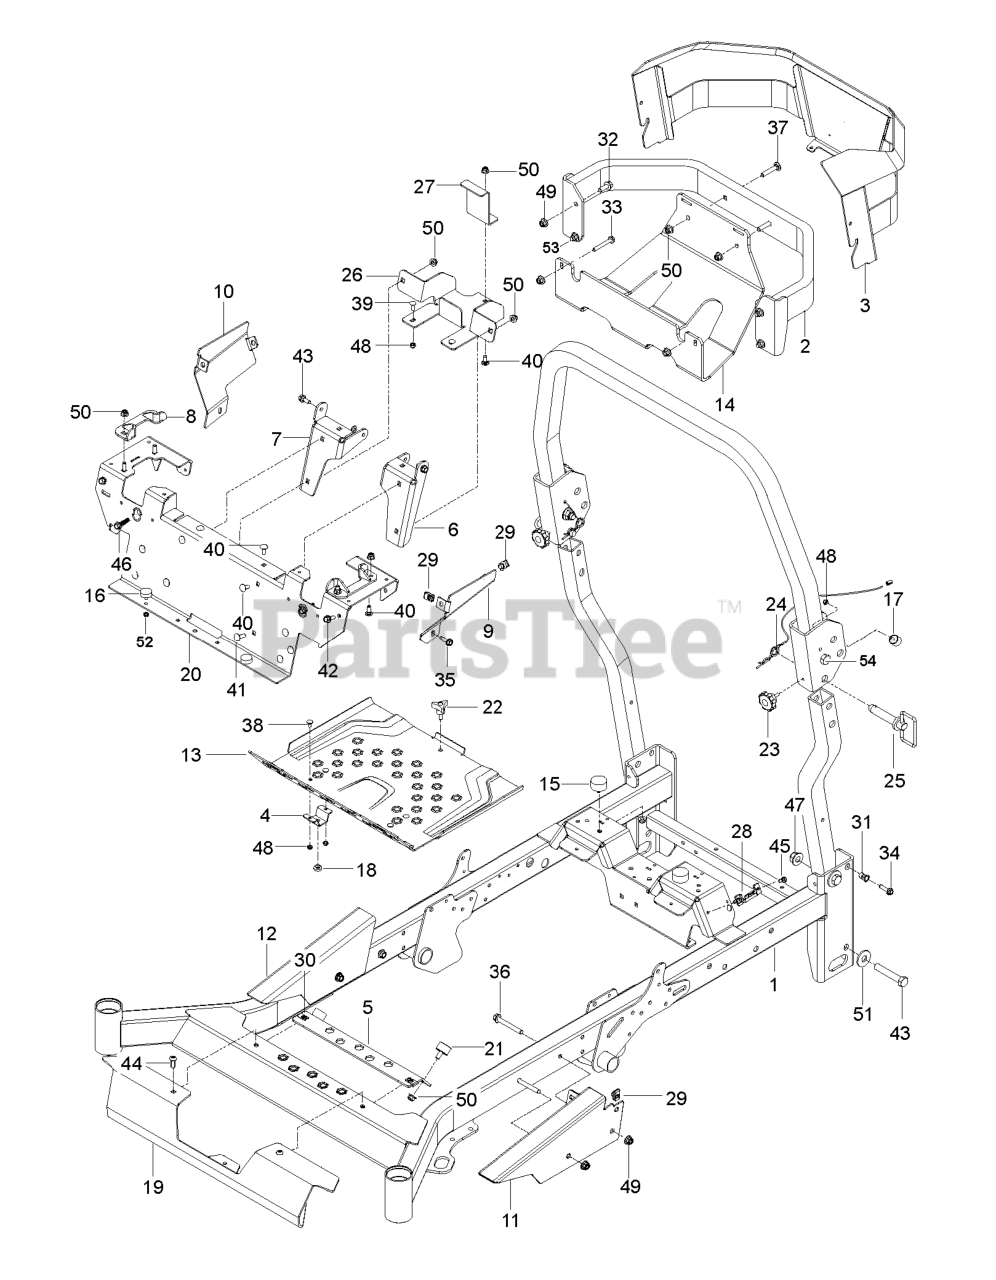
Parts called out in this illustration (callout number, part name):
1	FRAME.W/DECALS.48-60".ORG
2	BUMPER.REAR.ORANGE
3	GUARD.PNT.ENGINE.GREY
4	COVER.PNT.VALANCE.PZ.GREY
5	BRACKET.PNT.ISOLATOR.SUPPT.BLK
6	BRACKET.PNT.MTG.SEAT.LH.EDIP
7	BRACKET.PNT.MTG.SEAT.RH.EDIP
8	CABLE.YOKE.PARK.BRAKE
9	PANEL CLOSE OUT LH ORANGE MS-6
9	PANEL.PNT.CLOSE.OUT.LH.ORG
10	PANEL.PNT.CLOSE.OUT.RH.ORG
11	PANEL.PNT.WEDGE.LH.ORG
12	PANEL.PNT.WEDGE.RH.ORG
13	PLATE.PNT.FOOTREST.PZ.ORANGE
14	PLATE, SKID GRAY
14	PLATE SKID, Z500 LONG YAMAHA G
15	BUMPER 5/16-18
16	BUMPER, 1/4-20 STUD, 1/4
17	BUMPER, MALE STUD, 1/4-20
18	GROMMET, BUMPER
19	COVER.PNT.VALANCE.PZ.GREY
20	CROSS.MEMBER.PNT.SEAT.FRONT.OR
21	ISOLATOR.PZ.FOOTREST
22	KNOB W/STUD
23	KNOB.5/16-18X1"BLACK
24	PIN.HAIR.DOUBLE.LOOP.W/LANYARD
25	PIN.ROPS.W/HANDLE
26	PLATE.PNT.BATTERY.EDIP
27	Brackets
28	BRACKET.FUSE.RELAY.HOUSING.PZ
29	U-CLIP 5/16-18 NUT RETAINER
30	SCREW.BUTTON.HEAD.TORX.3/8-161
31	NUTSERT 5/16-18 THICK GRIP
32	HHFS 3/8-16 X 1 GRD 5 ZD
33	HHFS 5/16-18 X 2.25 GD 5
34	HHFS 5/16-18 X 1.25 TPBLT GD 5
35	RP BLT 5/16-18 X 1 THRD FORM D
36	HHFS 3/8-16 X 3 GRD 5 ZD
37	RHSNB 3/8C X 2
39	BOLT
39	1/4-20X3/4 CARR BLT
40	BOLT 5/16C X 3/4" CARRIAGE
41	RHSNB 5/16C X 1
42	BOLT, SHOULDER
43	5/8-11 X 3-1/2 HHB GRADE 5
44	SCREW.BUTTON.HEAD.TORX.3/8-161
45	SCREW
46	SCREW.SHAKEPROOF.1.25.BLACK
47	NUT 5/8-11 FLG NYLOC ZD
48	NUT.1/4-20.HEX.NYLOC.ZD
49	NUT 3/8-16 HEX FLG NYLOC ZD
50	5/16-18 NYLOC FLANGE NUT
51	WASHER, 5/8 FLAT
52	JAM NUT 1/4C (2 2 PW01)
53	BOLT.3/8-14X1.25
54	BOLT.HEXAG.5/8-11X4-1/4.G5.ZPY
